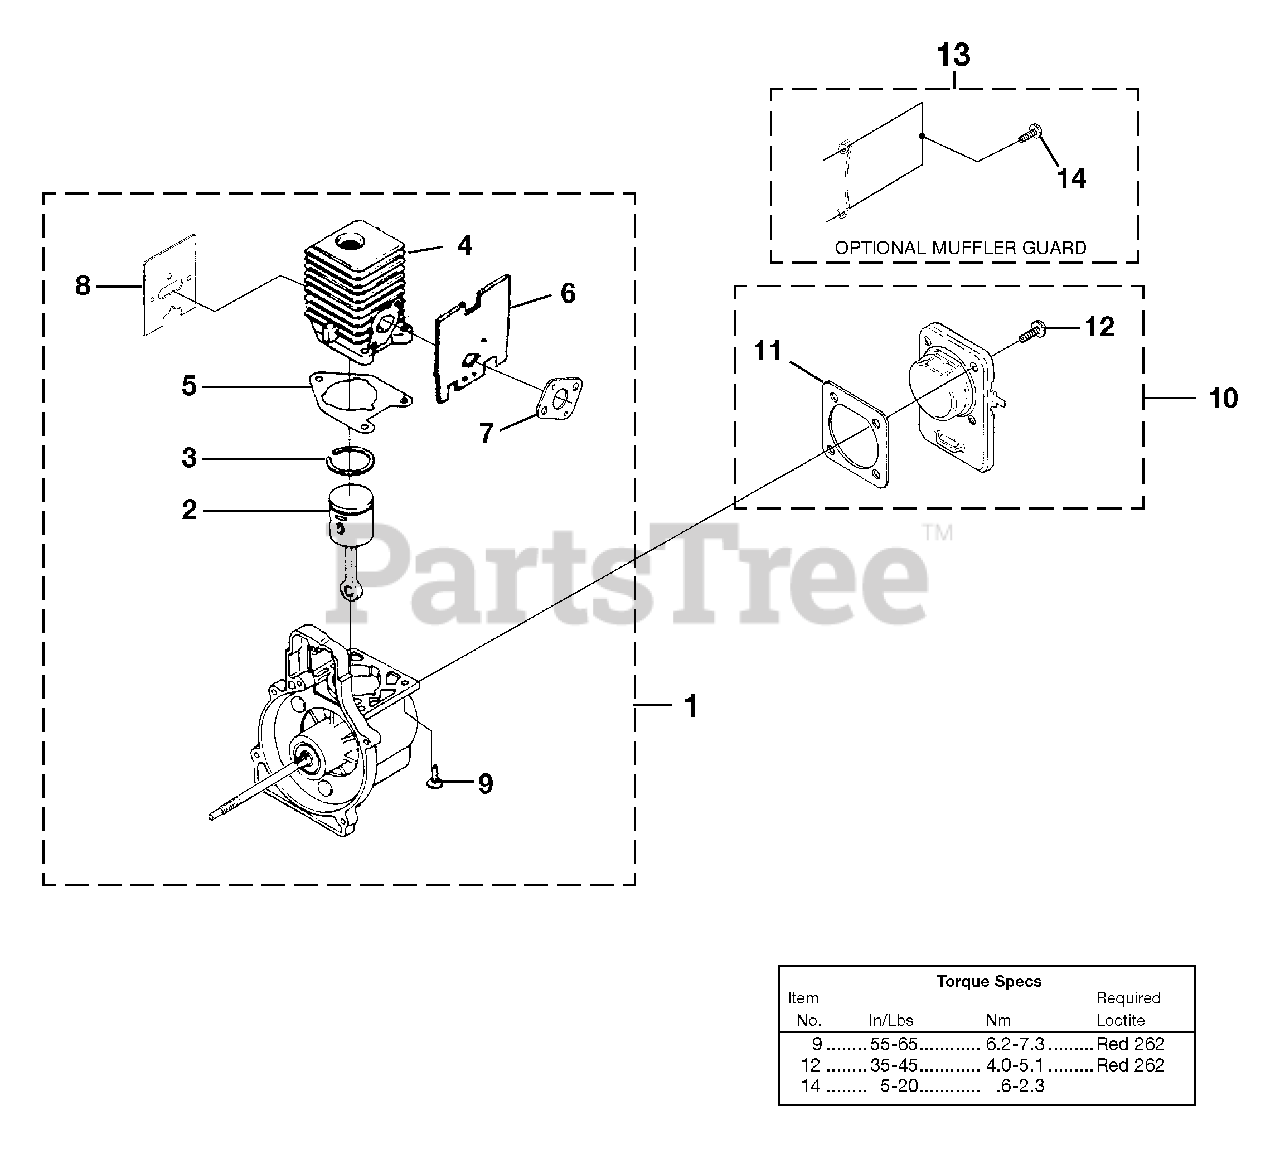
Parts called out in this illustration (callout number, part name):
1	SHORT BLOCK
2	PISTON & ROD ASSY.
3	RING-Piston
4	CYLINDER ASSY.
5	GASKET-Cylinder
6	GASKET-Heat Dam
7	GASKET-Carburetor
8	GASKET-Muffler
9	SCREW-Sems (12-24 X 3/4")
10	CRANKCASE COVER ASSEMBLY
11	GASKET-Crankcase Cover
12	SCREW-Sems (10-24 X 1/2")
13	MUFFLER GUARD
14	SCREW-Plastite (10-14 X 1/2")
